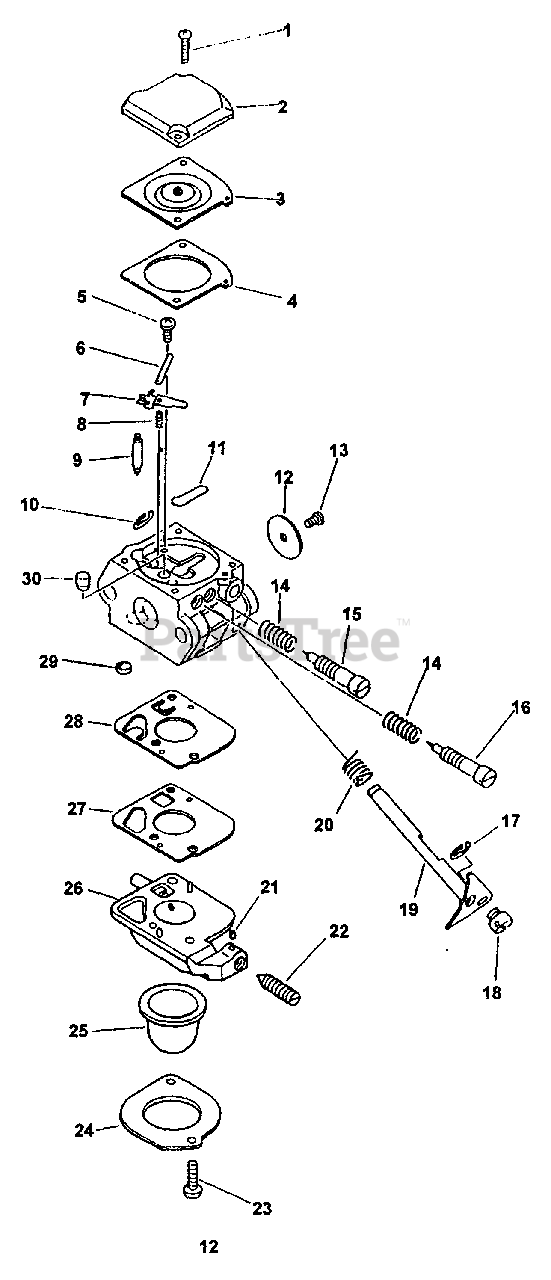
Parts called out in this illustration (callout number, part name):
2	COVER, DIAPHRAGM
3	DIAPHRAGM, METERING
4	GASKET, METERING
6	PIN
7	LEVER, METERING
8	SPRING, METERING LEVER
9	VALVE, NEEDLE
11	PLUG, WELCH
12	VALVE, THROTTLE
14	SPRING, NEEDLE
15	NEEDLE, LOW SPEED
16	NEEDLE, HIGH SPEED
19	SHAFT, THROTTLE
20	SPRING, THROTTLE RETURN
21	PIECE, FRICTION
22	SCREW, IDLE ADJUST
24	RETAINER
25	BULB, PURGE
26	BODY ASSY, PURGE
29	STRAINER
30	NOZZLE, CHECK VALVE
